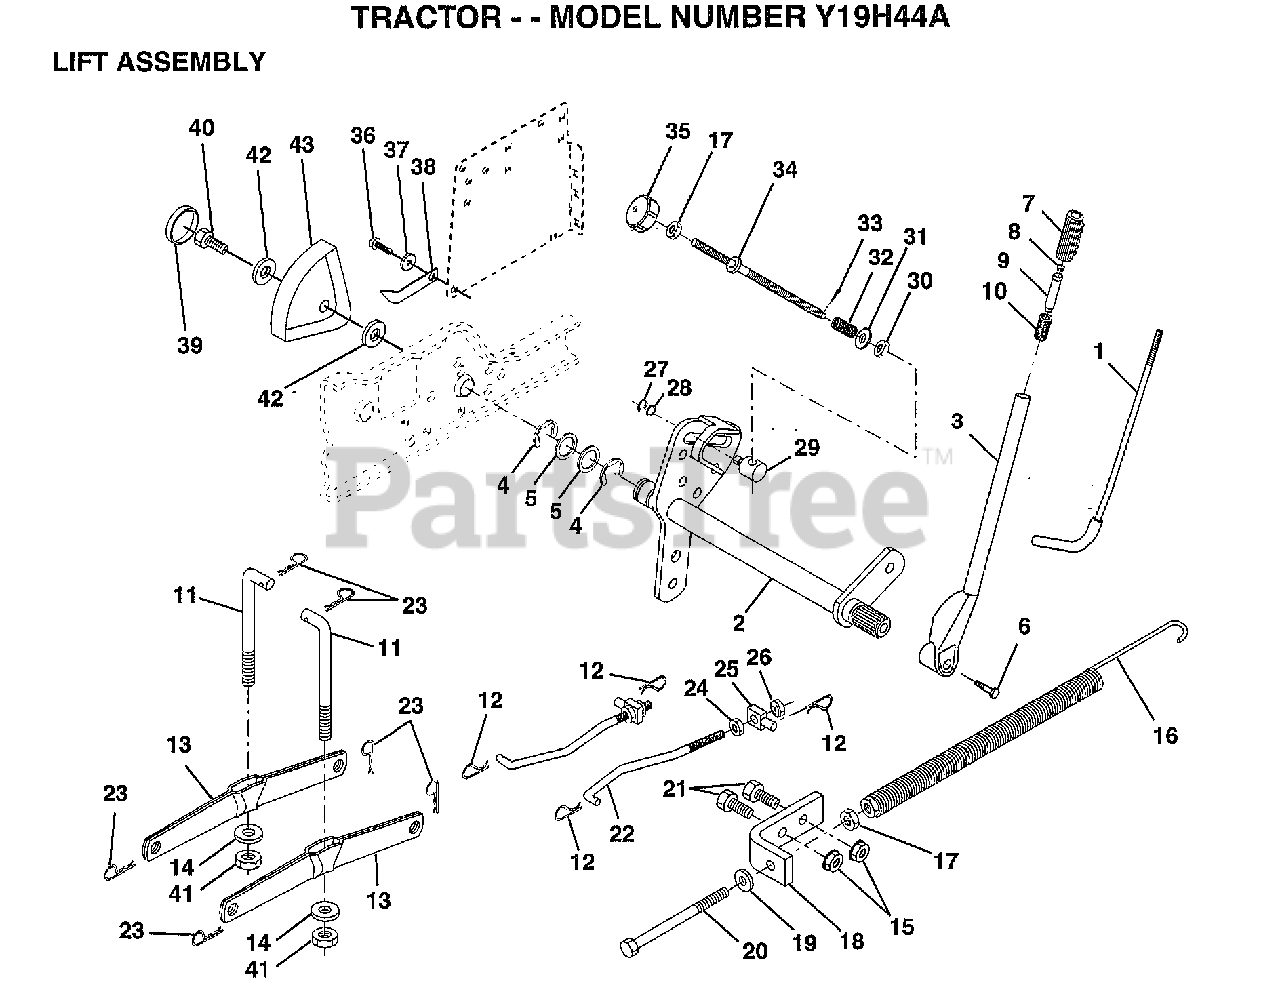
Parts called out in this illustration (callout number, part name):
1	LEVER ROD LT
2	SHAFT.LIFT.VGT.95
4	E-RING
5	WASHER
6	"BOLT,HEX"
7	GRIP
10	SPRING T
11	LINK.LIFT.MWR.VGT
12	RETAINER.SPRING
13	ARM SUSP REAR
14	BEARING PVT LH
17	NUT
18	BRACKET SPRING AS
19	WASHER
20	BOLT-ADJ SPRING T
21	BOLT
22	LINK.FRONT
24	NUT
25	TRUNION
26	NUT.LK.W/WSH.1/2.
27	KLIP RING
28	WASHER
29	TRUNION LT
30	NUT T
31	WASHER
32	SPRING.COMP.INF.H
34	ROD.ADJ.LIFT
35	KNOB INF 3/8-16
36	SCREW
37	WASHER T
38	POINTER HGT IND
39	"PLUG,HOLE"
40	SCREW
41	NUT.CROWNLOCK.3/8
42	WASHER
43	HEIGHT INDICATOR
